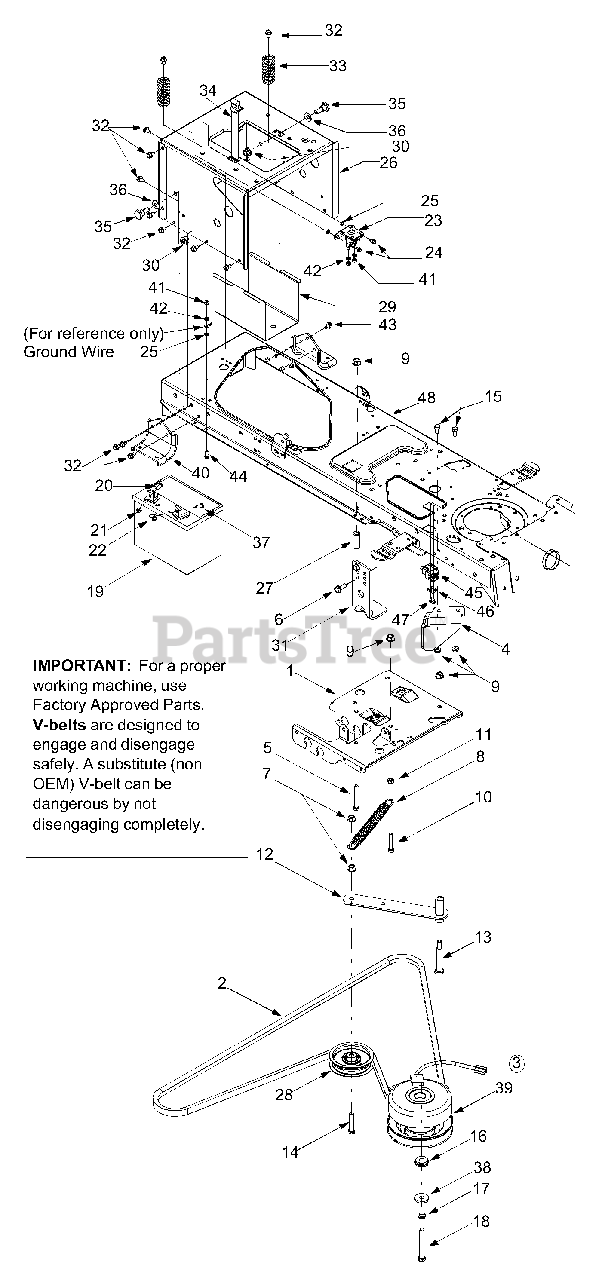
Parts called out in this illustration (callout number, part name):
2	PTO Belt
3	Elec. PTO Clutch
3	Washer, Flat 1.031 x 1.62 x .095
6	Hex Hd Wash. Screw, 5/16-18 x .875
7	Flange Lock Nut, 3/8-16
8	Extension Spring, .62 x 5.62
9	Flange Lock Nut, 5/16-18
10	Hex Cap Screw, 5/16-18 x 1.75
11	Hex Nut, 5/16-18
14	Hex Cap Screw, 3/8-16 x 2.0
15	Hex Cap Screw, 5/16-18 x .625
16	Shoulder Spacer, 1.38 x .445 x .36
17	Lock Washer, 7/16
18	Hex Cap Screw, 7/16-20 x 3.25
19	12-volt Battery, 270 CCA
20	Hex Cap Screw, 1/4-20 x .62
21	Hex Sems Nut, 1/4-20
22	Wing Nut, 1/4-20
23	Solenoid, 12-Volt, 100 Amp
24	Self Tapping Screw, 1/4-20 x .5
25	Lock Washer, 1/4
28	Idler Pulley, 3.5
32	Self Tapping Screw, 5/16-18 x .625
33	Compression Spring, 1.28 x 3.5
34	Battery Strap
35	Shoulder Screw, .625 x .5, 7/16-20
36	Bell Washer, .45 x 1.0 x .062
37	Shoulder Screw, 1/4-20, .25 x .15
38	Flat Washer, .45 x 1.25 x .164
39	Harness Assembly, PTO Clutch
41	Hex Nut 1/4-20
42	Lock Washer
43	TT Screw 5/16-18 x 0.5
44	TT Screw 1/4-20 x 0.75
45	Switch
46	Switch Plate
47	AB Screw #10-16 x 0.5
